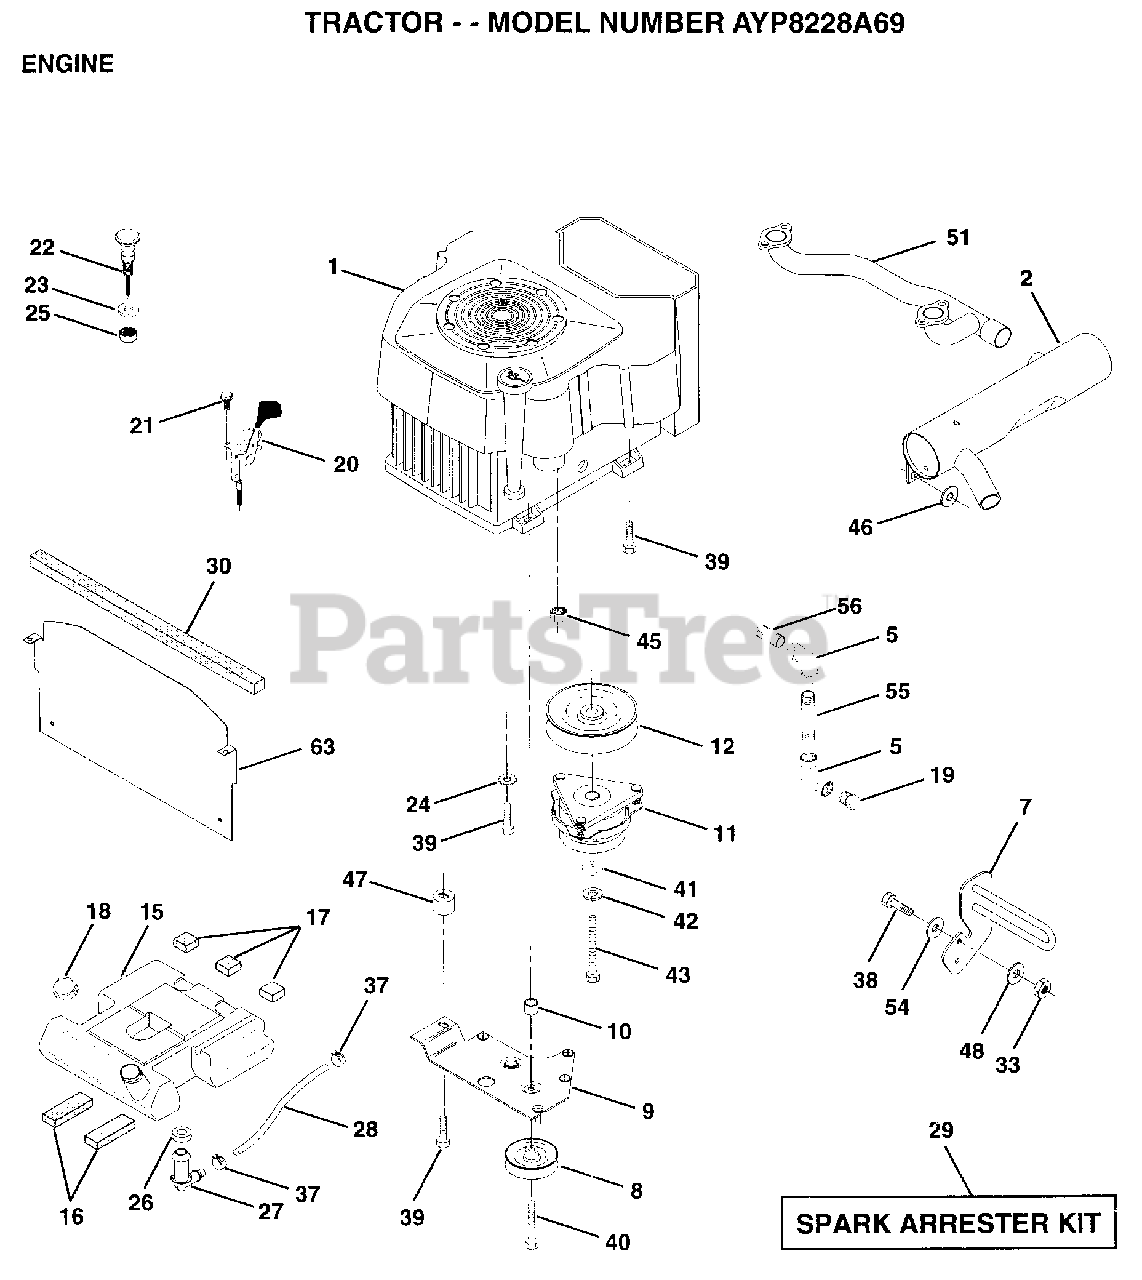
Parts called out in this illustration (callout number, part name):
1	ENGINE, KOHLER
5	ELBOW
10	BUSHING.
12	PULLEY.ENG.CLUTCH
16	PAD IDLER TI
18	CAP ASM FUEL
19	PLUG T
21	SCREW LT
22	CHOKE CONTROL
23	WASHER
24	LOCKWASHER
26	BUSHING OUTLET T
27	STEM.TANK.FUEL
29	SPARK ARREST KIT
30	FOAM-STRIP LT
33	NUT
37	HOSE CLAMP
38	"BOLT,HEX"
39	SCREW.3/8-16X2.25
40	SCREW.TT.3/8-16X4
41	WASHER
42	LOCKWASHER
43	BOLT.7/16-20X4.25
45	NUT
46	WASHER HYT
47	SPACER.ENGINE
54	WASHER
56	NIPPLE.PIPE
63	HEAT.SHIELD.VGT.
188	WASHER T
